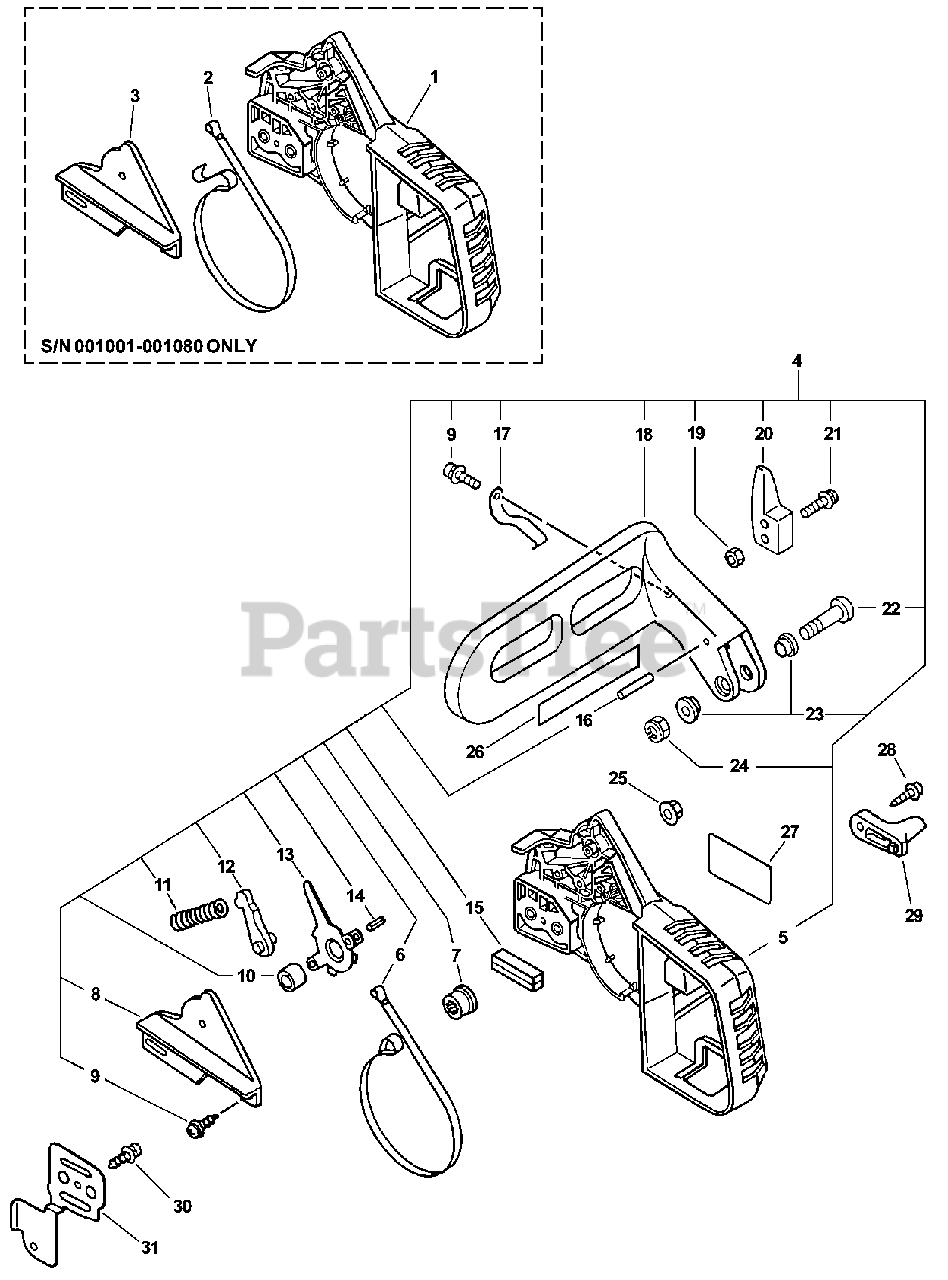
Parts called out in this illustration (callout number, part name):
1	GUARD, SPROCKET
2	BAND, BRAKE
3	COVER, BRAKE
4	CHAIN BRAKE ASSY
5	GUARD, SPROCKET
6	BAND, BRAKE
7	ADJUSTER, BRAKE BAND
8	COVER, BRAKE - GRAY
9	SCREW - 4X10
10	SPACER - 8
11	SPRING, BRAKE
12	STOPPER, BRAKE
13	LEVER, BRAKE
14	PIN - SPRING -- 4X8
15	SEAL
16	ROLLER - 4X23.8
17	SPRING, RETURN
18	LEVER, BRAKE
19	NUT - 4
20	WEIGHT, BRAKE
21	SCREW - 4X20
22	SCREW - 5X30
23	SPACER
24	LOCKNUT - 5
25	NUT - 6 -- FLANGE
26	LABEL - BAR & CHAIN -- US
26	LABEL - BAR & CHAIN -- CANADA
27	LABEL - MODEL
28	SCREW - 5X20 -- TAPPING
29	CATCHER, CHAIN
30	SCREW - 4X10
31	PLATE, GUIDE - OUTER
